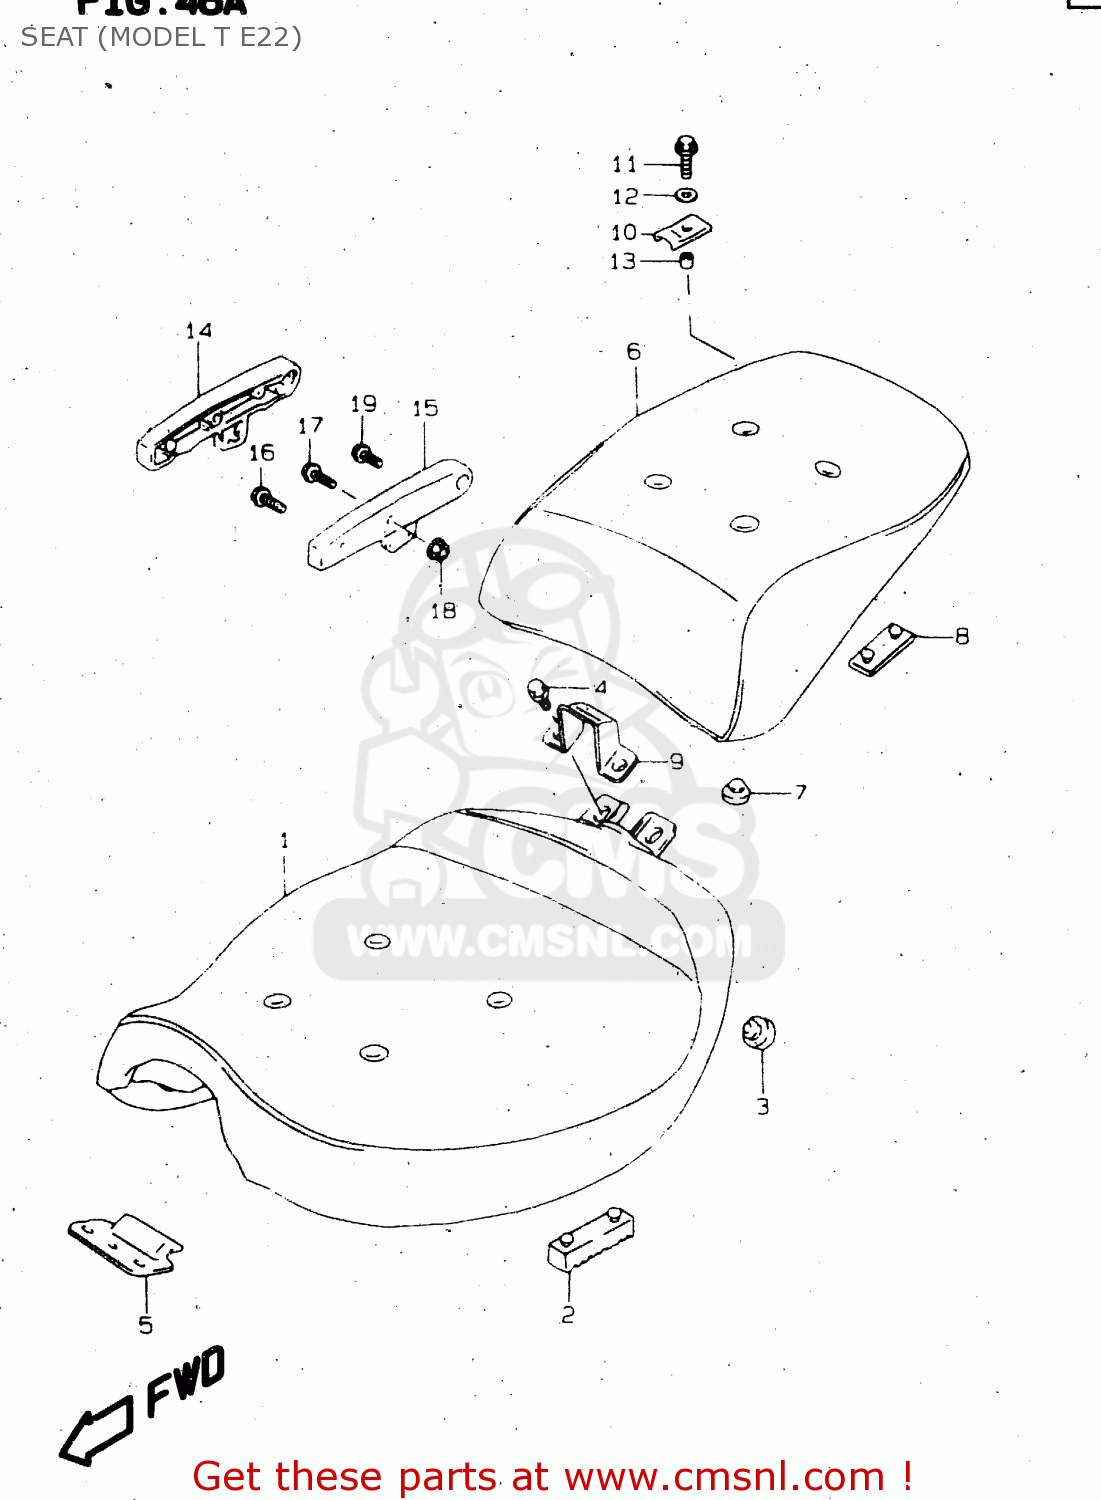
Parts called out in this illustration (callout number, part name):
1	SEAT ASSY
2	CUSHION,SEAT
3	CUSHION
4	BOLT
5	BRACKET,SEAT FR
6	SEAT ASSY,PILLION
7	CUSHION
8	CUSHION,PILLION SEAT RR
9	BRACKET,PILLION SEAT FR
10	PLATE,PILLION SEAT RR
11	BOLT
12	WASHER(6.5X18X1.6)
13	SPACER(6.5X8.5X5.8)
14	HANDLE,PILLION RIDER,R
15	HANDLE,PILLION RIDER,L
16	BOLT, FRONT
17	BOLT
18	NUT
19	BOLT, REAR
